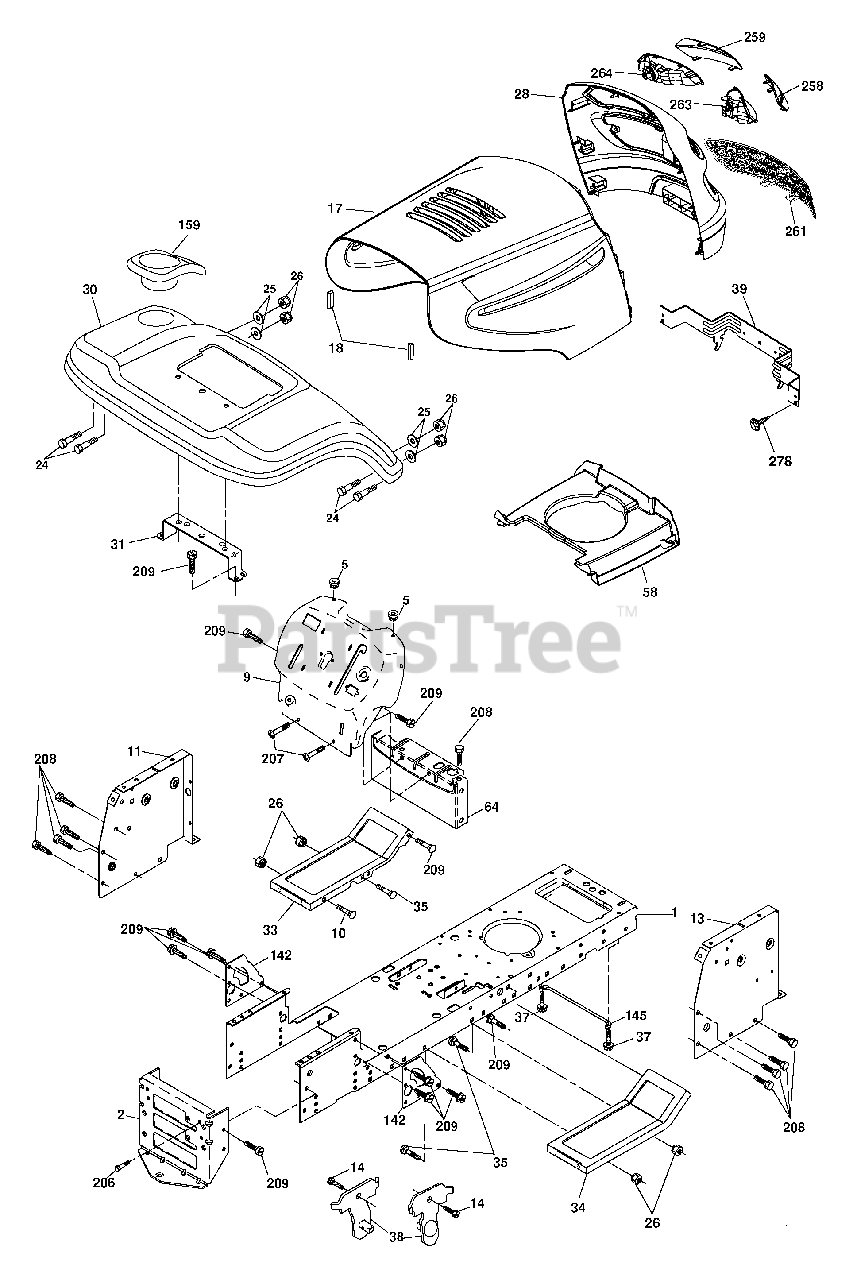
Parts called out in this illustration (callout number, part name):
1	Chassis
2	Drawbar
5	Bumper Hood/Dash
9	Dash P/L
10	Bolt Carriage 3/8-16 x 1
11	Panel Dash Lh
14	Screw Thdrol 3/8-16 x 1/2
17	Hood
18	Bumper Hood
24	Bolt Fin Hex 3/8-16 unc x 1 Gr. 5
25	Washer 13/32 x 3/4 x 12 Ga.
26	Nut Lock Hex W/Ins 3/8-16 unc
28	Grille/Lens Asm
30	Fender
31	Bracket Fender
33	Footrest LH
34	Footrest RH
35	Bolt RDHD STH SQNK 3/8-16 x 3/4
37	Screw Thdrol 6/16-18 x 1/2 TYT
38	Bracket Asm Pivot Mower Rear
39	Bracket Pivot
58	Duct Air
64	Dash Lower STLT
142	Plate Reinforcement STLT
145	Rod Pivot Chassis/Hood
159	Cupholder
206	Bolt Shoulder 5/16-18
207	Screw Thdrol 5/16-18 x 1/2
208	Screw Thdrol 3/8-16 x 1/2
209	Screw Hexwsh Thdr 3/8-16 x 3/4
258	Lens Grille Pro RH
259	Lens Grille Pro LH
263	Bezel Grille RH
264	Bezel Grille LH
278	Screw 10 x 3/4 Single Lead Hex
